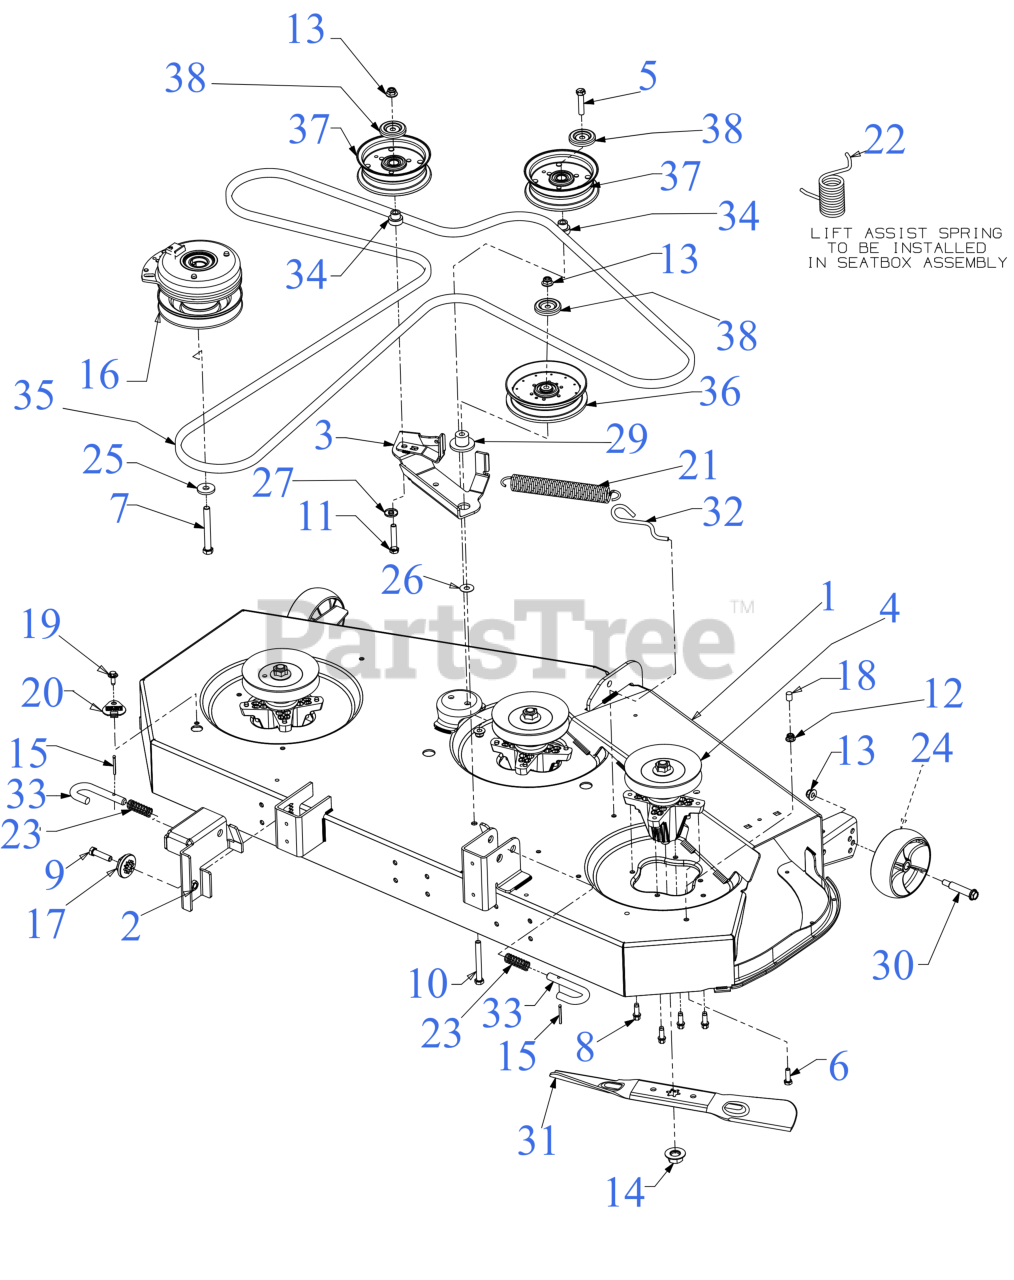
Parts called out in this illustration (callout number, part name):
1	54"FAB DECK SHELL
3	DECK IDLER ASSEMBLY
4	SPINDLE ASSEMBLY
4	Cub Cadet 54" SPINDLE (06978 W/HDW)
5	HEX SCREW 3/8-16 x 1.75 GR5
6	SCREW 5/16-18 x 1.0 GR5
7	SCREW 7/16-20 x 3.5 GR5
8	SCREW 5/16-18 x .875
9	SCREW 3/8-16X1.5 GR5
10	SCREW 3/8-16 x 3.25 GR8
11	SCREW 3/8-16 x 2.0 GR5
12	FLANGE LOCK NUT 5/16-18
15	COTTER PIN-5/32 DIA
16	ELECTRIC PTO CLUTCH
17	DECK ADJUSTMENT GEAR
19	SCREW M6-1 x .625
20	DECK WASH PLUG
21	EXTENSION SPRING
22	TORSION SPRING
23	COMPRESSION SPRING .66 OD x 1
24	DECK WHEEL (5.0 DIA x 1.875)
25	FLAT WASHER .445 x 1.248 x .170
26	FLAT WASHER
29	SHOULDER SPACER
30	SHOULDER BOLT (.50 X 2.0 x 3/8 -16)
31	18.61" BLADE (2N1)
32	DECK SPRING HOOK
33	DECK RELEASE PIN
34	SHOULDER SPACER
35	V-BELT B SEC x 148.25
36	FLAT IDLER PULLEY
37	IDLER PULLEY 4.50" DIA
38	IDLER PULLEY CAP
